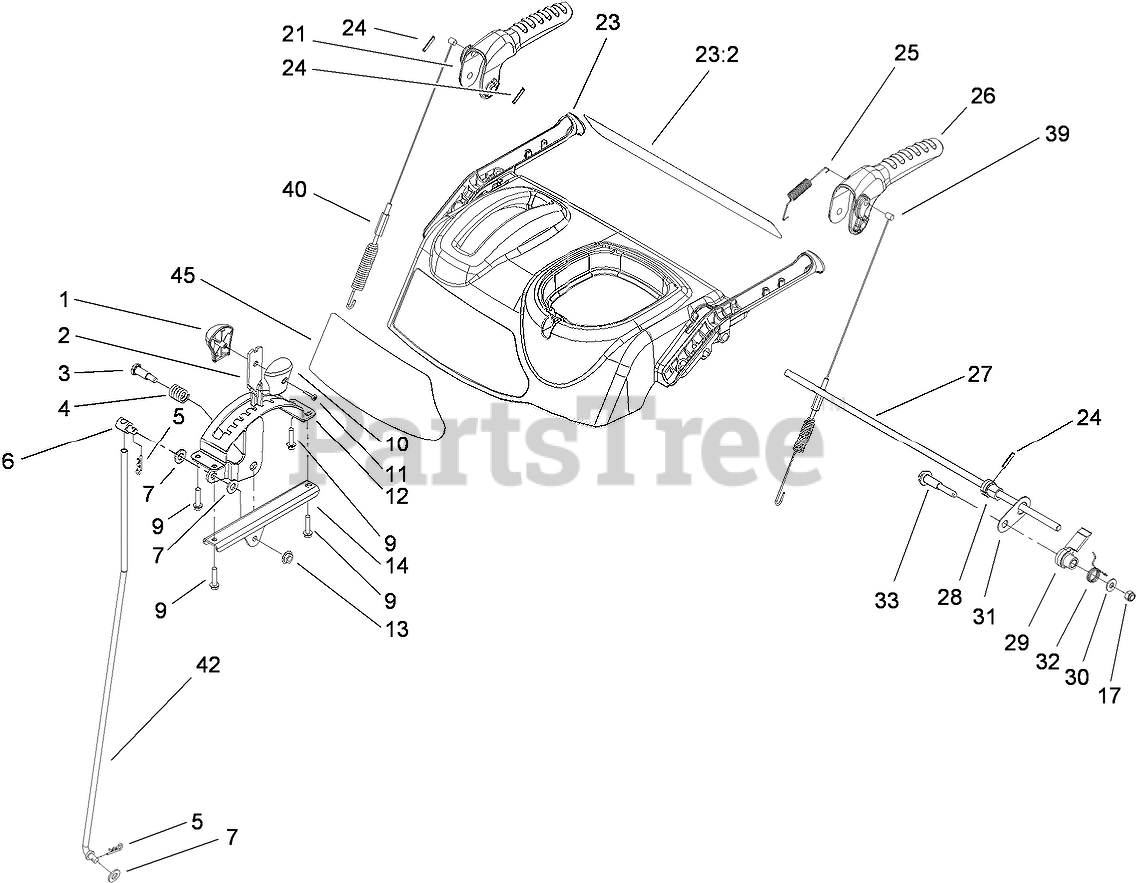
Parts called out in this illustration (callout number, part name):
1	KNOB-SHIFT, RH
2	SELECTOR-SPEED
3	SCREW-SHOULDER
4	SPRING-COMPRESSION
5	PIN-COTTER
6	TRUNNION-ROD
7	WASHER-FLAT
9	SCREW-PLASTITE
10	KNOB-SHIFT, LH
11	SCREW-PPH
12	GUIDE-SELECTOR, SPEED
13	NUT-HF
14	MOUNT-SELECTOR, SPEED
17	NUT-LOCK, NI
21	LEVER-AUGER
23	CONTROL PANEL ASM
23:2	DECAL-PANEL, CONTROL
24	PIN-SPRING
25	SPRING-TENSION
26	LEVER-TRACTION
27	ROD-LOCKOUT
28	CAM-LOCKOUT
29	LATCH-LOCKOUT
30	WASHER-FLAT
31	LINK-LOCKOUT
32	SPRING-TORSION
33	SCREW-SHOULDER
39	CABLE-TRACTION
40	CABLE-AUGER
42	ROD-SHIFT
45	DECAL-CONTROL PANEL
